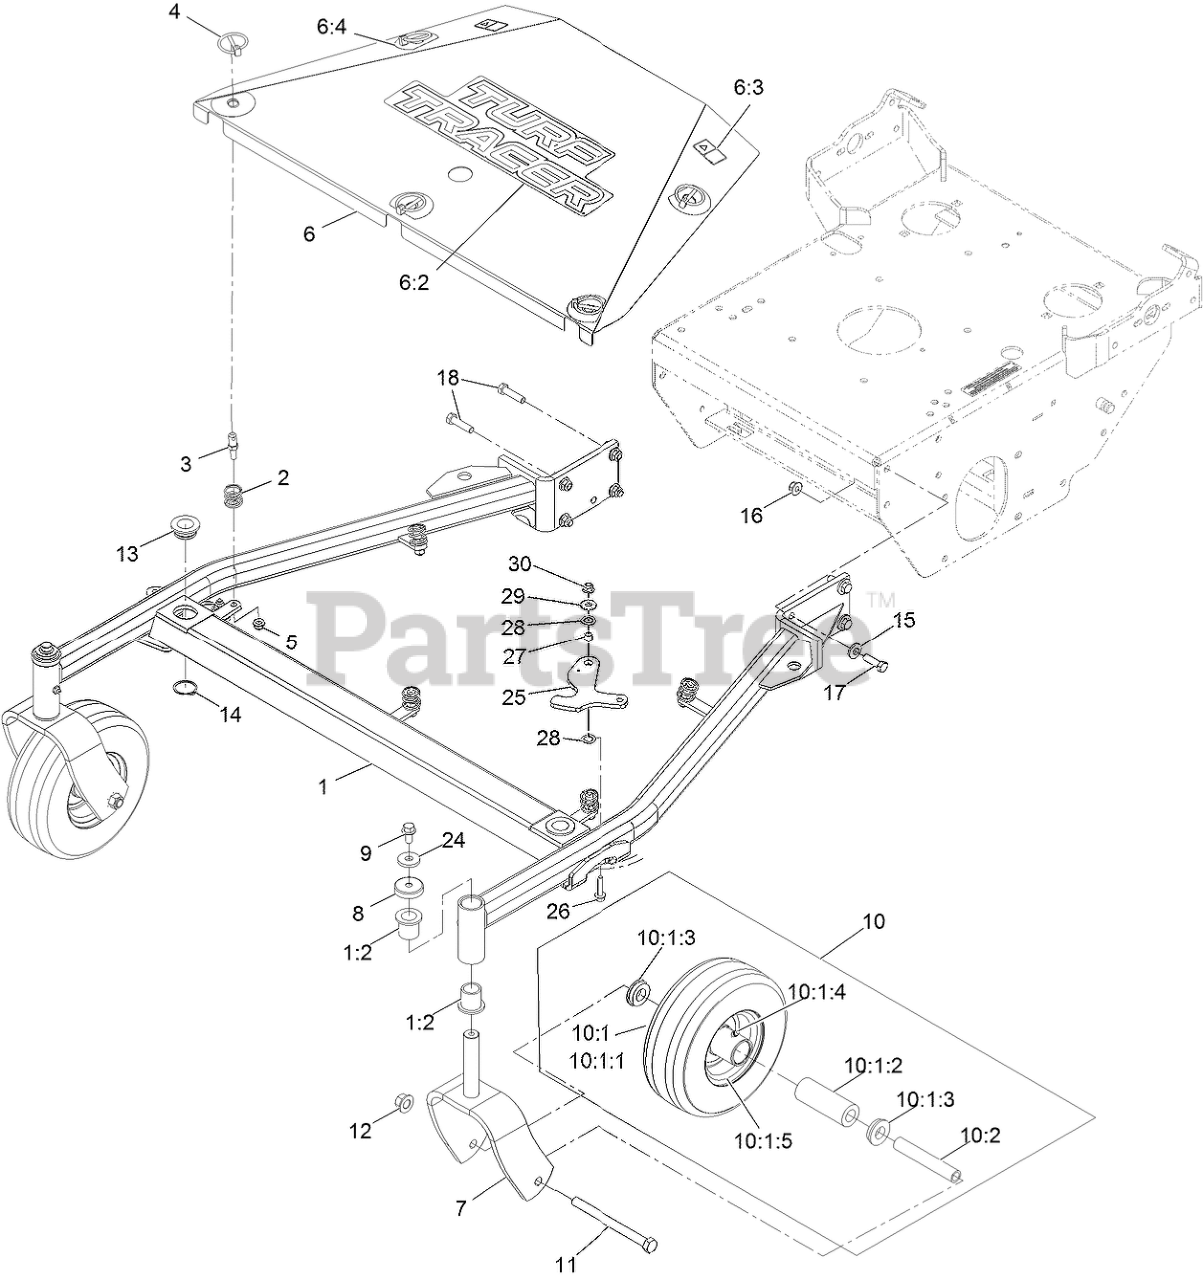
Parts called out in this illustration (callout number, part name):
1	ASM, FRAME W/ BUSHINGS, 4
1:2	BEARING-FLANGED
3	PIN-SPRING
4	PIN-LYNCH
5	NUT-HF, NI
6	ASM, SHIELD W/ DECALS, 48
6:2	DECAL-TURF TRACER
6:3	DECAL-WARNING
6:4	DECAL-SCRATCH COVER
7	FORK, CASTER
8	CAP, DUST
9	SCREW-HHF
10	KIT, SP CASTER WHEEL REPL
10:1	Wheel And Tire ASM
10:1:1	Tire
10:1:2	BEARING
10:1:3	BUSHING
10:1:4	FITTING-GREASE
10:1:5	Wheel
11	SCREW-HH
12	Nut-Lock 1/2-13
13	BUSHING-DECK
14	RING-RETAINING
15	WASHER-BELLEVILLE
16	NUT-HF, NI
17	SCREW-HH
18	SCREW-HH
25	LATCH, DECK HEIGHT
26	Screw-HHF
27	Spacer-Grommet
28	WASHER-CONICAL
29	WASHER-FLAT
30	NUT-HF, NI
